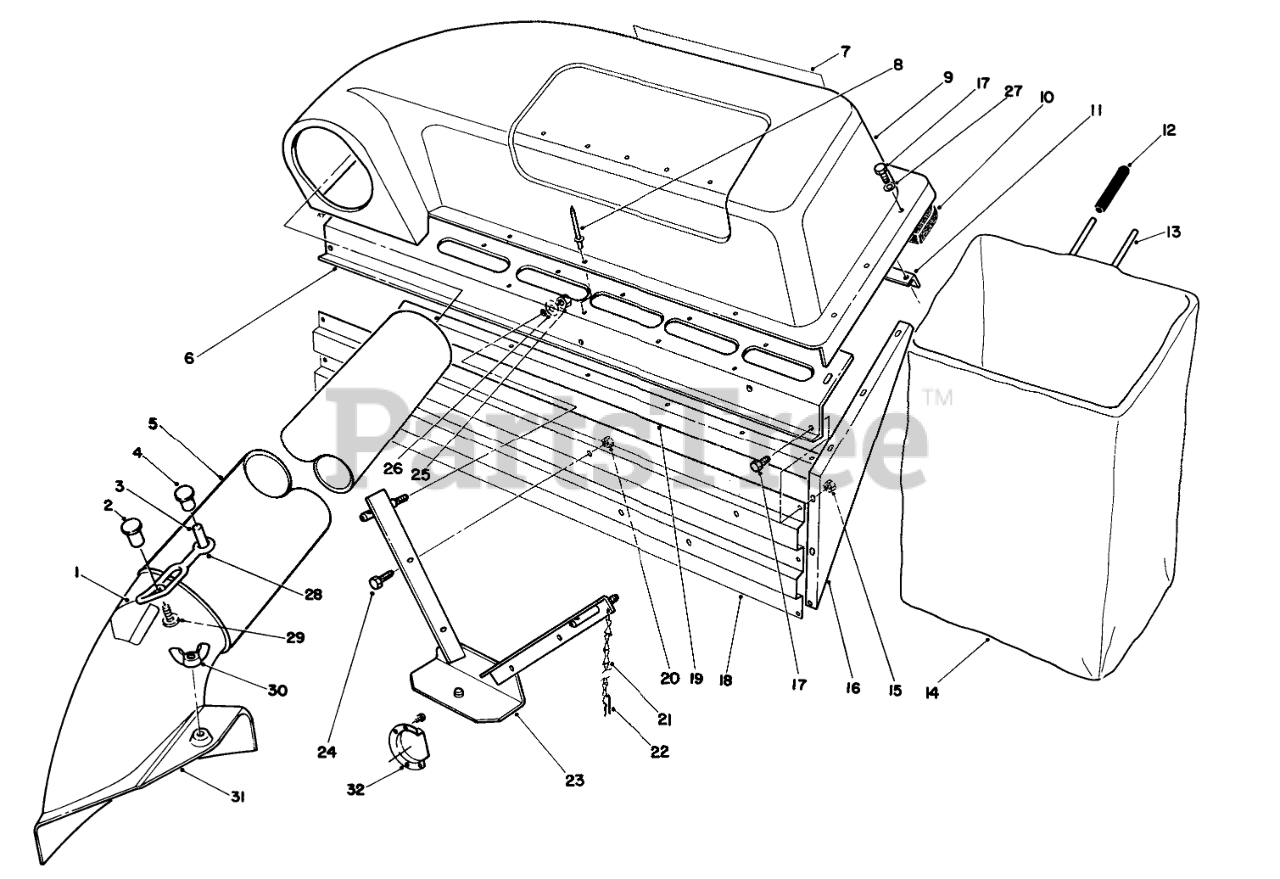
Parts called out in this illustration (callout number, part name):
1	DECAL-DANGER
3	SPACER-INTERLOCK
4	Fastner-Panel
6	COVER SUPT BAFFLE B
7	Decal-Twin Bagger
8	RIVET-POP
9	COVER
10	FOAM SEAL
11	BAG FRAME BRKT
12	GRIP-HANDLE, BAG
13	BAG FRAME
15	NUT-LOCK, NI
16	Plate-Side
17	SCREW-HH
18	COVER
19	BAG SUPPORT CHANNEL
20	NUT-LOCK, NI
21	6-LINK CHAIN W/HOOK
22	PIN-HAIR
23	V-Bracket
24	SCREW-HH
25	NUT-LOCK, NI
26	WASHER-FLAT
27	WASHER-FLAT
28	RETAINER-DUCT
29	Screw
30	NUT-WING SPECL
31	Assembly-Chute (Incl. Ref. #1, 2 & 29)
32	MUFFLER DEFLECTOR
